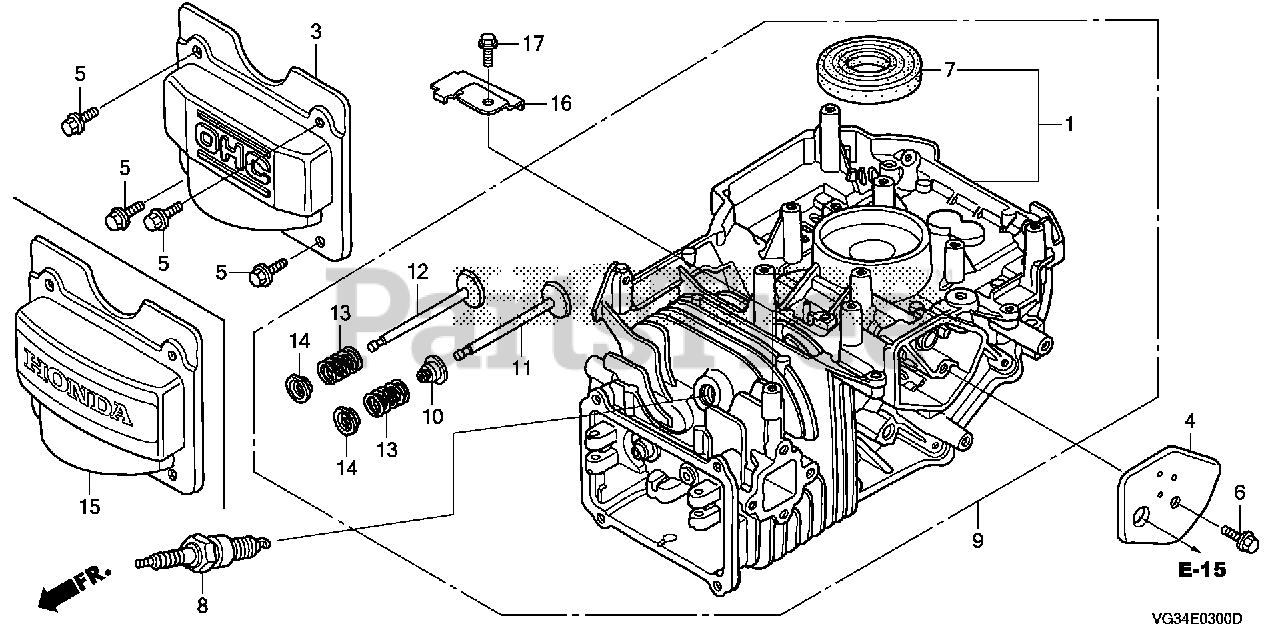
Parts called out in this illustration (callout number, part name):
1	CYLINDER ASSY.
3	COVER, CYLINDER HEAD
3	COVER, HEAD
4	COVER, BREATHER (BREATHER VALVE ASSY.)
5	BOLT, FLANGE (6X12) (CT200)
6	BOLT, FLANGE (6X14) (CT200)
7	OIL SEAL (25.4X62X6)
8	SPARK PLUG (BPR6ES) (NGK)
10	SEAL, VALVE STEM
11	VALVE, IN. (TECHNOSTAR)
12	VALVE, EX. (L8E)
12	VALVE, EX. (C8E)
13	SPRING, VALVE
14	RETAINER, IN. VALVE SPRING (IN./EX.)
14	RETAINER, VALVE SPRING
